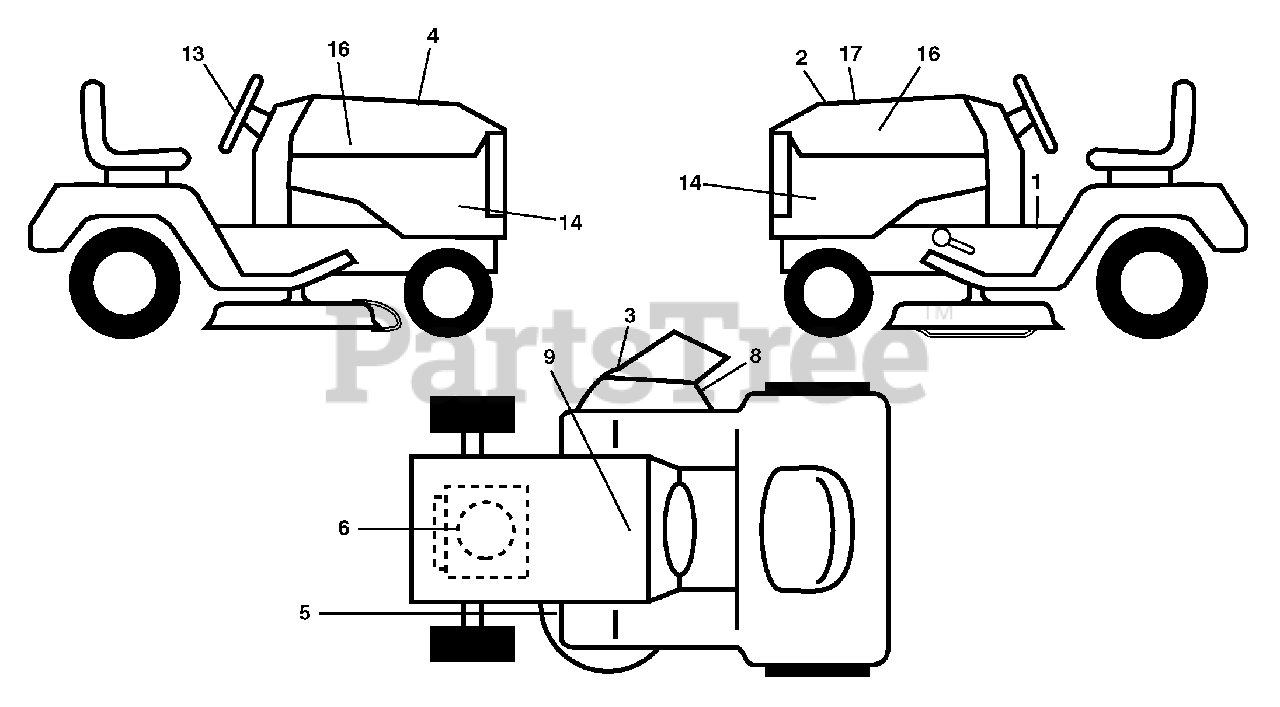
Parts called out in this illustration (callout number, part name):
1	Decal, Operator's
2	Decal, Hood Insert
3	Decal, Warning
4	Decal, Hood Cust Resp.
5	Decal, Caution
6	Decal, Engine
8	Decal, Mower Sch.
9	Decal, Battery Dnge/Poi
13	Decal, Steering Whl
14	Decal, Panel Side
16	Decal, Hood Logo
17	Decal, Replacement
